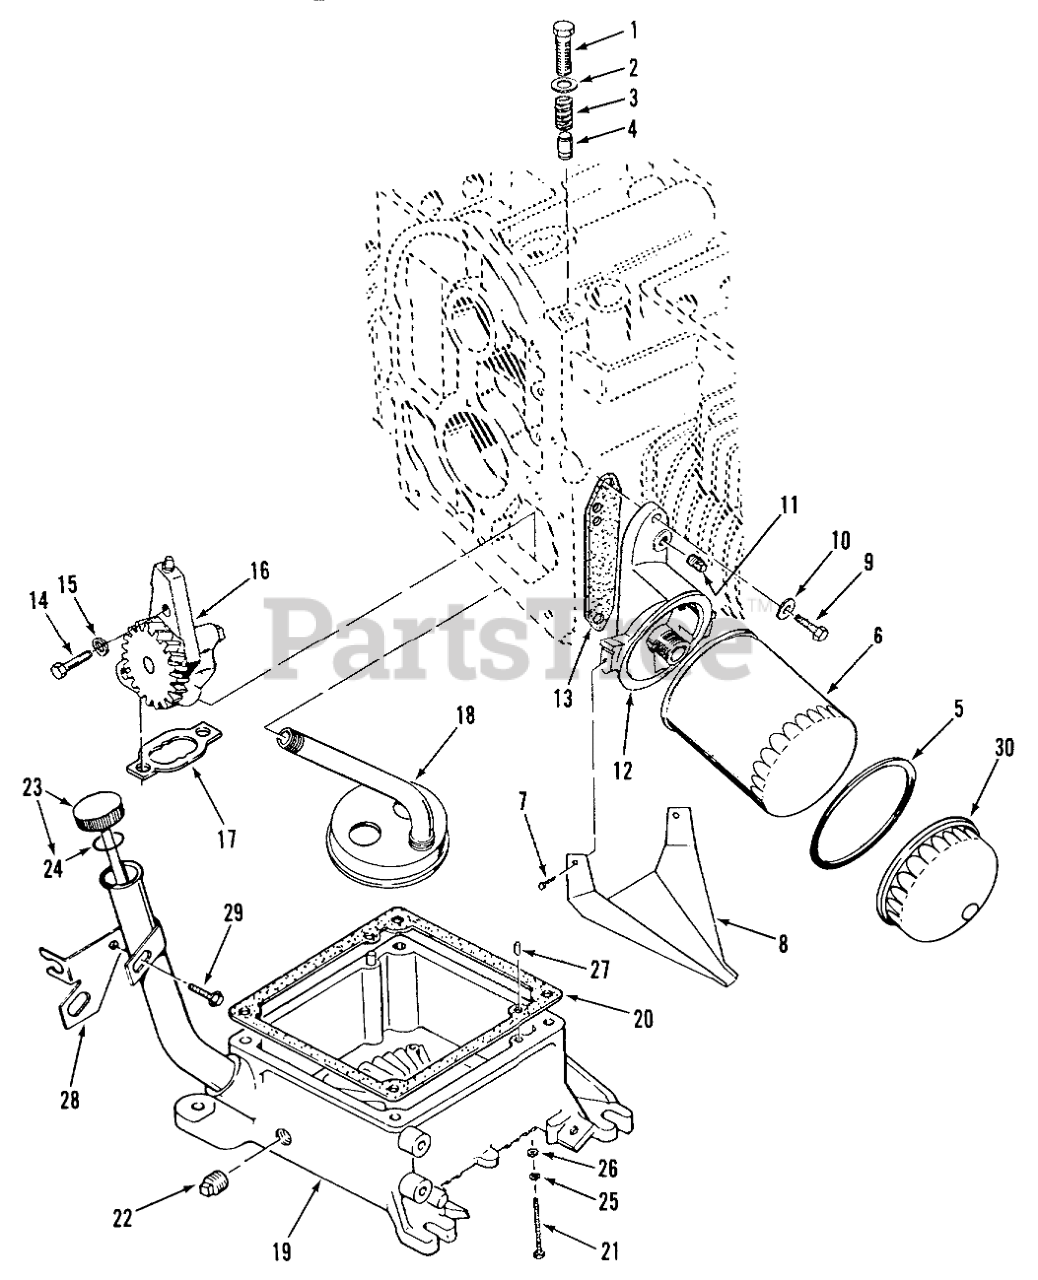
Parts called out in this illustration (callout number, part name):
1	Bolt
2	Washer
3	Spring
4	Piunger
5	Oil Fiter Seal
6	OIL FILTER
7	Bolt
8	OIL DRAIN
9	HHCS 5/16-18 X 1
10	Washer
11	Plug
12	Adapter
13	Gasket
14	Bolt
15	Washer-Lock
16	Oil Pump
17	Oil Pump Gasket Kit
18	INTAKE OIL PUMP CUP
19	Oil Base (includes Drain Plug and Dowel Pin)
20	Gasket
21	HEX HEAD CAP SCREW
22	Plug
23	OIL FILL CAP & IND
24	O-Ring
25	Lockwasher 3/8
26	FLAT WASHER
27	Dowel Pin
28	OIL TUBE SUPPORT
29	Bolt
30	Oil Filter Wrench
